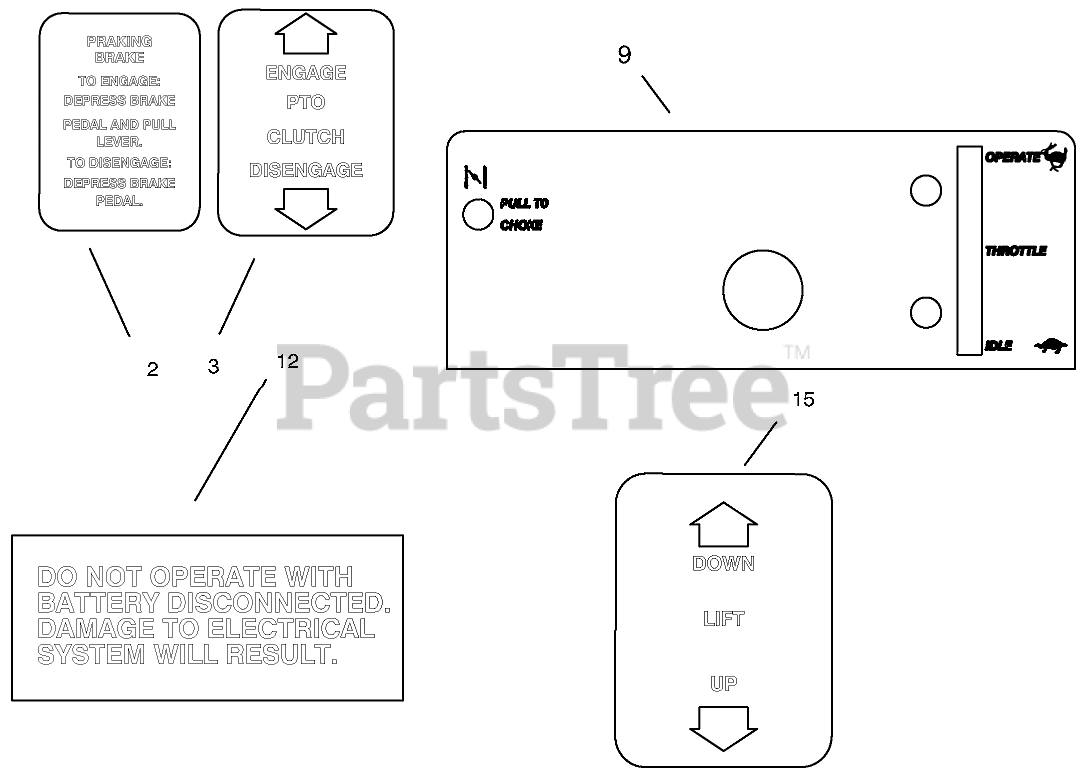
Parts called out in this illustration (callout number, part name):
2	DECAL-PARKING, BRAKE
2	DECAL - PARKING BRAKE
3	DECAL PTO CLUTCH
3	DECAL - PTO CLUTCH
9	DECAL-LOWER DASH
9	DECAL - LOWER DASH
12	DECAL ELECT SYSTEM
12	DECAL - ELEC SYSTEM
15	DECAL-LIFT
15	DECAL - LIFT
